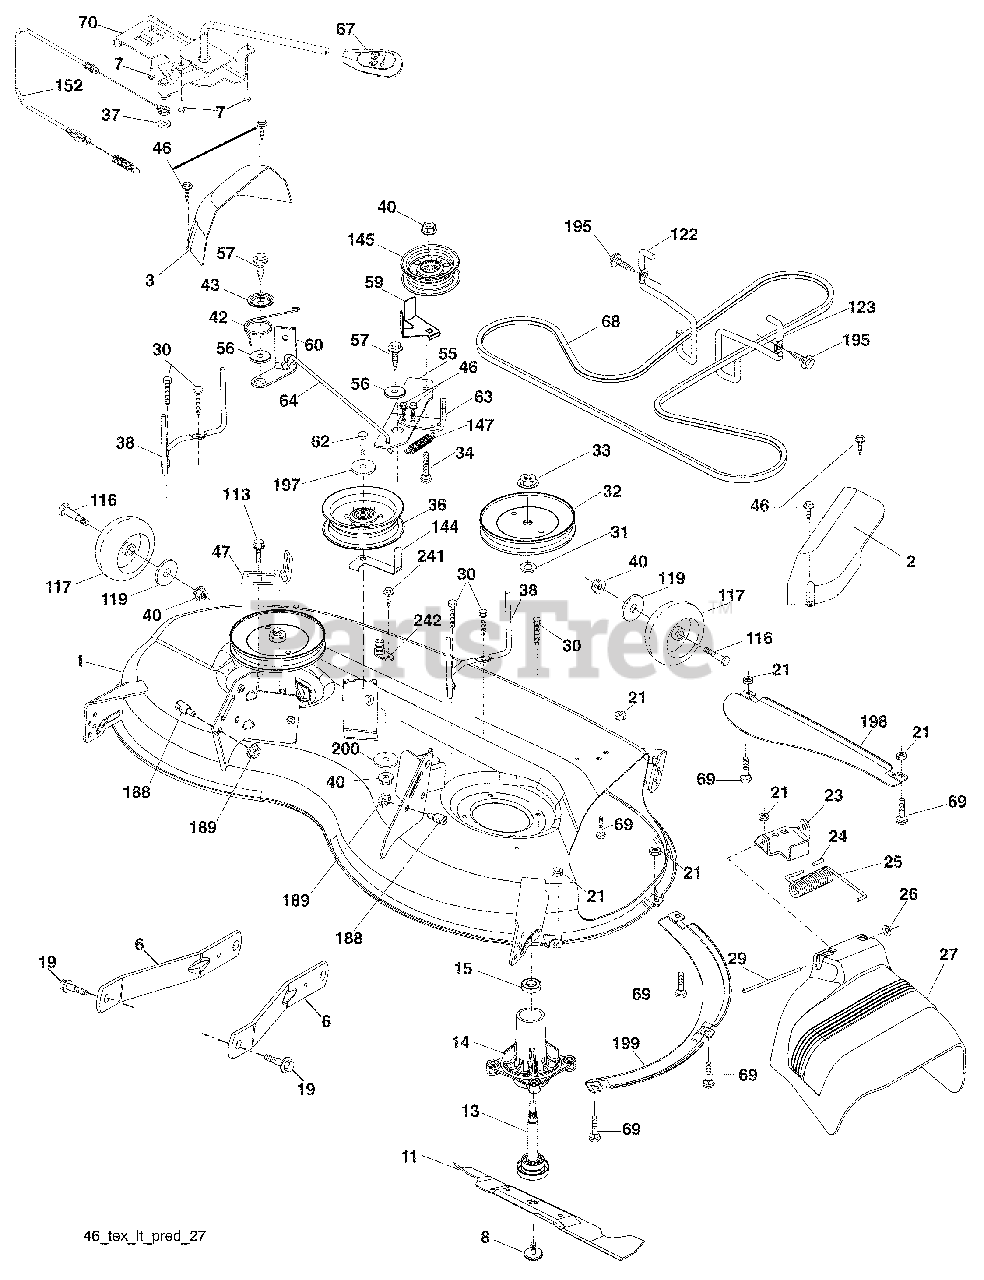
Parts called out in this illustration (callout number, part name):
1	Mower Housing
2	Cover Mandrel RH
3	Cover Mandrel LH
6	Arm Suspension
7	Screw #10 x 0.750
8	Bolt/Washer Asm 7/16-20 unf
11	Blade Mower
13	Shaft Assembly, Mandrel
14	Housing, Mandrel
15	Bearing, Ball, Mandrel
19	Bolt, Shoulder
21	Nut
23	Bracket, Deflector
24	Cap, Sleeve
25	Spring, Torsion, Deflector
27	Shield, Deflector
29	Rod, Hinge
30	Screw Thdrol Rolling Wsh Hd
31	Washer, Spacer
32	Pulley, Mandrel
33	Nut, Toplock, Flanged
34	Bolt Carr Sh. 3/8-16 x 1-1/2 Gr. 5
36	Pulley, Idler, Flat
37	Washer 13/32 x 13/16 x 16 Ga.
38	Keeper Belt LH Mandrel
40	Nut, Lock Flg. 3/8-16 unc
42	Spring Trosion Brake
43	Spring Torsion Retainer
47	Bracket Clutch Cable
55	Arm, Idler
56	Spacer, Retainer
57	Screw Hexwsh Thd 3/8-16 x 1
59	Guard, Tuv Idler (94)
60	Arm Brake Mower LH
62	Bolt 3/8-16 unc x 2-1/4 Gr. 5
63	Arm Brake Mower
64	Linkage Brake
67	Handle, Clutch Cable
68	V-Belt
70	Clutch Asm. Cable
113	Screw 5/16-18
116	Bolt, Shoulder
117	Wheel, Gauge
119	Washer 13/32 x 1-1/4 x 12 Ga.
122	Keeper Belt Eng. LH
123	Keeper Belt Eng. RH
144	Keeper Belt
145	Pulley Idler
147	Spring Return
152	Cable Clutch Manual w/Spr.
188	Stud Fastener
189	Nut Lock Hex Flange
195	Screw 3/8-16 x 3/4
197	Washer 13/32 x 13/16 x 12 Ga.
198	Baffle Center Front
199	Baffle Front RH
200	Washer 13/32 x 1 x 1/2 11 Ga.
242	Washout Port
